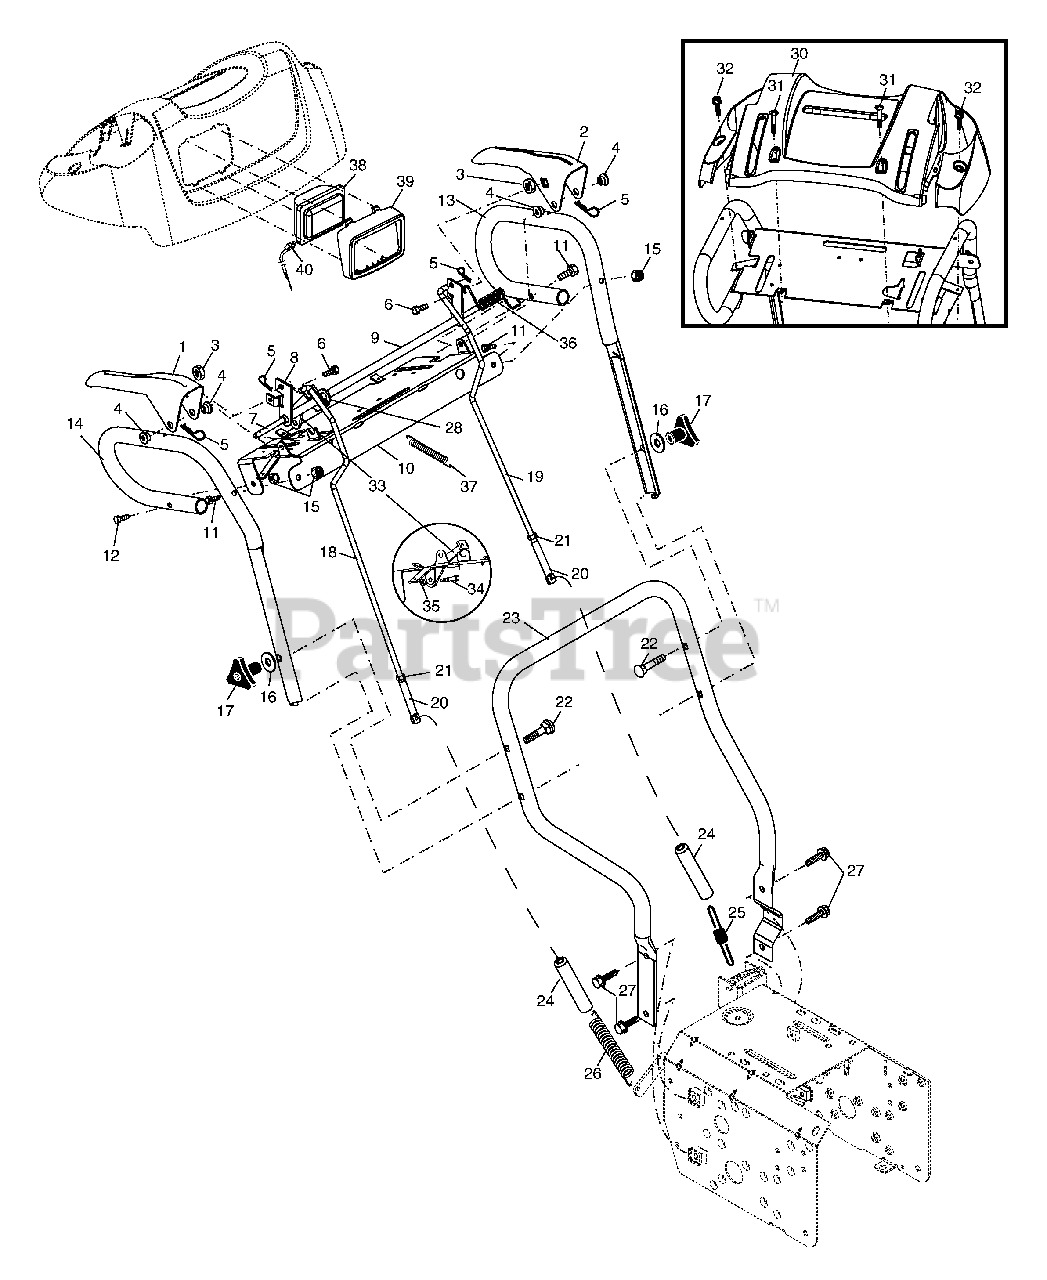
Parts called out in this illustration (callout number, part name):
1	Lever, Auger Control, RH
2	Lever, Traction Drive Control, LH
3	Nut, Cage 1/4-20
4	Bushing, Flange
5	Retainer, Hairpin
6	Screw, Hex Head 1/4-20 x 3/4
7	Rod, Interlock
8	Tube Assembly, Interlock, RH
9	Tube Assembly, Interlock, LH
10	Panel, Control
11	Screw, Hex Head 5/16-18 x 1-1/2
12	Screw, Hex Head 5/16-18 x 1-3/4
13	Handle Tube, LH
14	Handle Tube, RH
15	Nut, Lock 5/16-18
16	Washer, Flat 3/8
17	Knob, Handle
18	Rod, Auger Control
19	Rod, Traction Control
20	End, Control Rod
21	Nut, Hex, Jam 5/16-18
22	Bolt, Carriage 3/8-16 x 2-1/4
23	Handle Tube, Lower
24	Sleeve, Spring
25	Spring, Traction Drive
26	Spring, Auger Control
27	Screw, Hex Head 3/8-16 x 1
28	Clip, Panel
30	Console, Panel
31	Screw, Hex Head, Tapping #10-24 x 1-1/4
32	Screw, Hex Head, Tapping #10-24 x 1/2
33	Latch, Interlock
34	Bolt, Shoulder
35	Nut, Lock 1/4-20
36	Spring, Torsion
37	Spring, Interlock
38	Headlight, Flood
39	Bezel, Headlight
40	Harness, Headlight (Flood)
